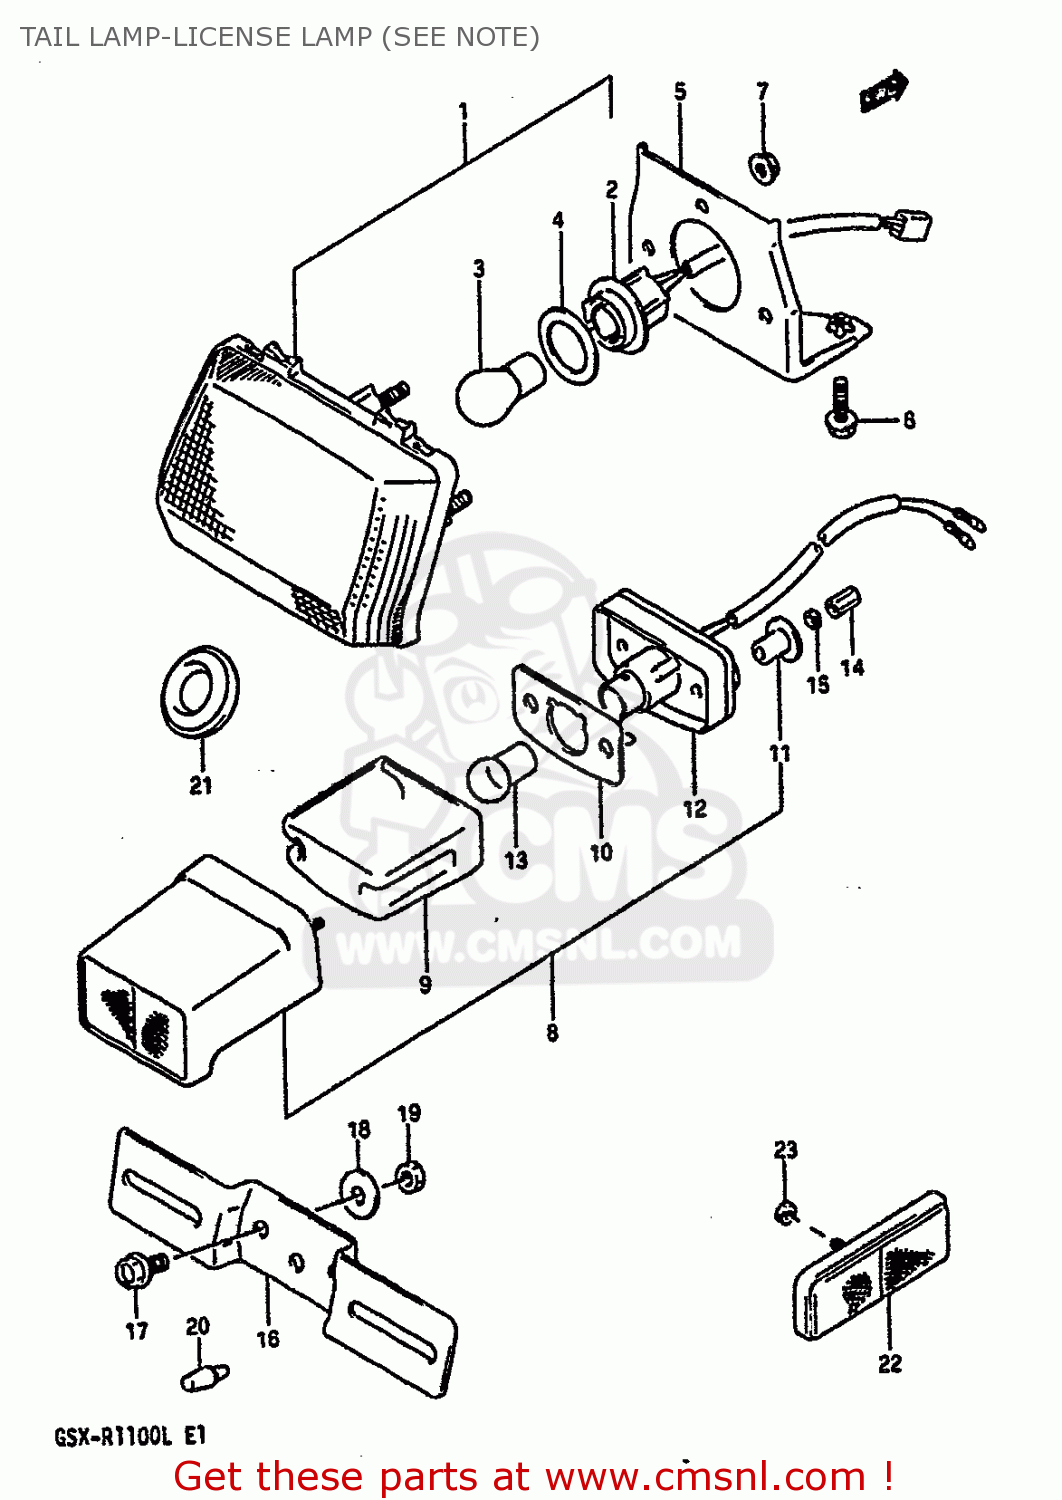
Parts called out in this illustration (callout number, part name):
1	LAMP ASSY,RR C
2	SOCKET
3	BULB(12V21/5W)
4	CUSHION,RUBBER
5	BRACKET COMP,REAR COMBINATION LAMP
6	BOLT
7	NUT
8	LAMP ASSY,LICE
9	LENS
10	GASKET,LICENSE LAMP (NAS)
11	SPACER
12	HOUSING
13	BULB(12V5W,BF150-40160A)
14	NUT
15	LOCK WASHER
16	BRACKET,LICENSE PLATE
17	BOLT
18	WASHER
19	NUT
20	CUSHION
21	CAP OD:40
22	REFLEX REFLECTOR,FR SIDE
23	NUT 5MM
